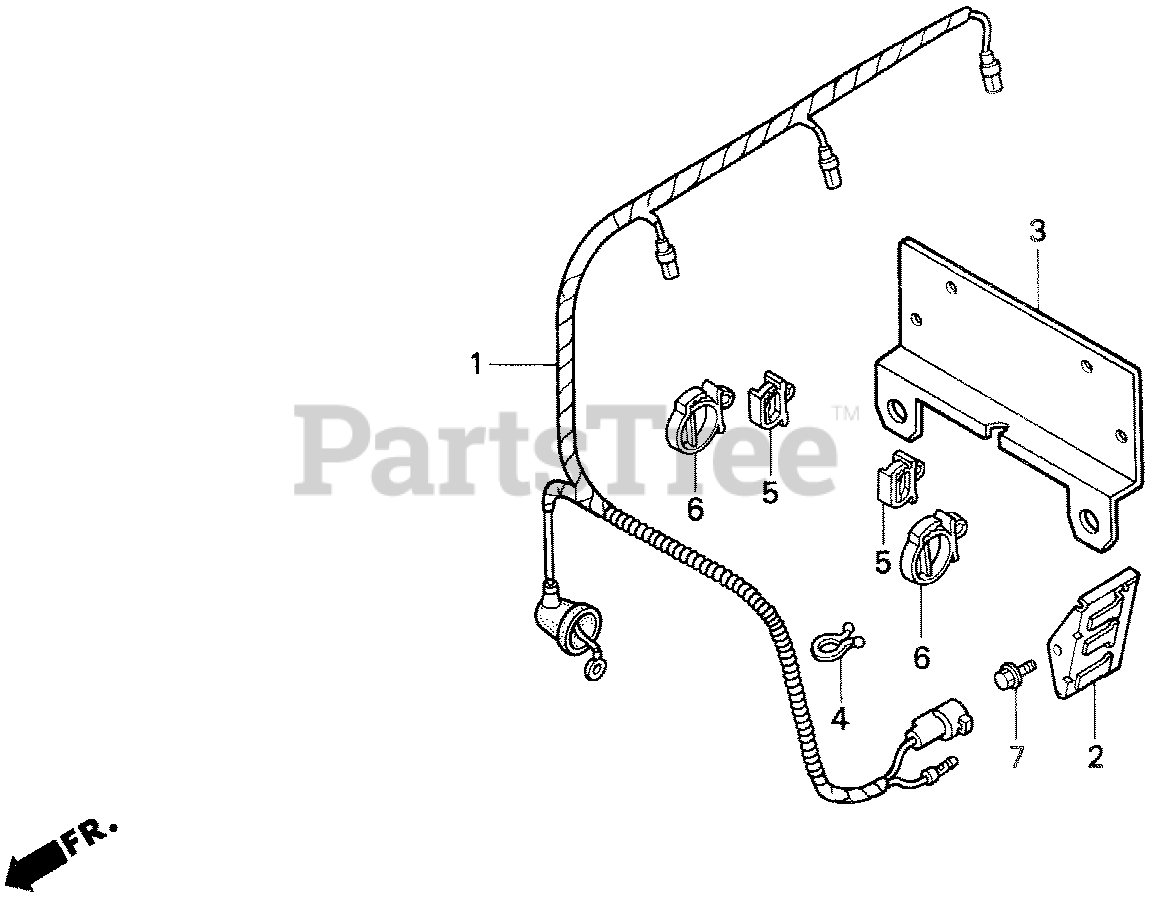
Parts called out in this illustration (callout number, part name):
1	CABLE ASSY., GLOW PLUG
2	BRACKET, CONNECTOR
3	BRACKET, HARNESS CLIP
4	CLIP, PURSE LOCK
5	CLIP, WIRE HARNESS (10MM)
6	STRAP, WIRE HARNESS (25MM) (BLACK)
7	BOLT, FLANGE (6X12)
